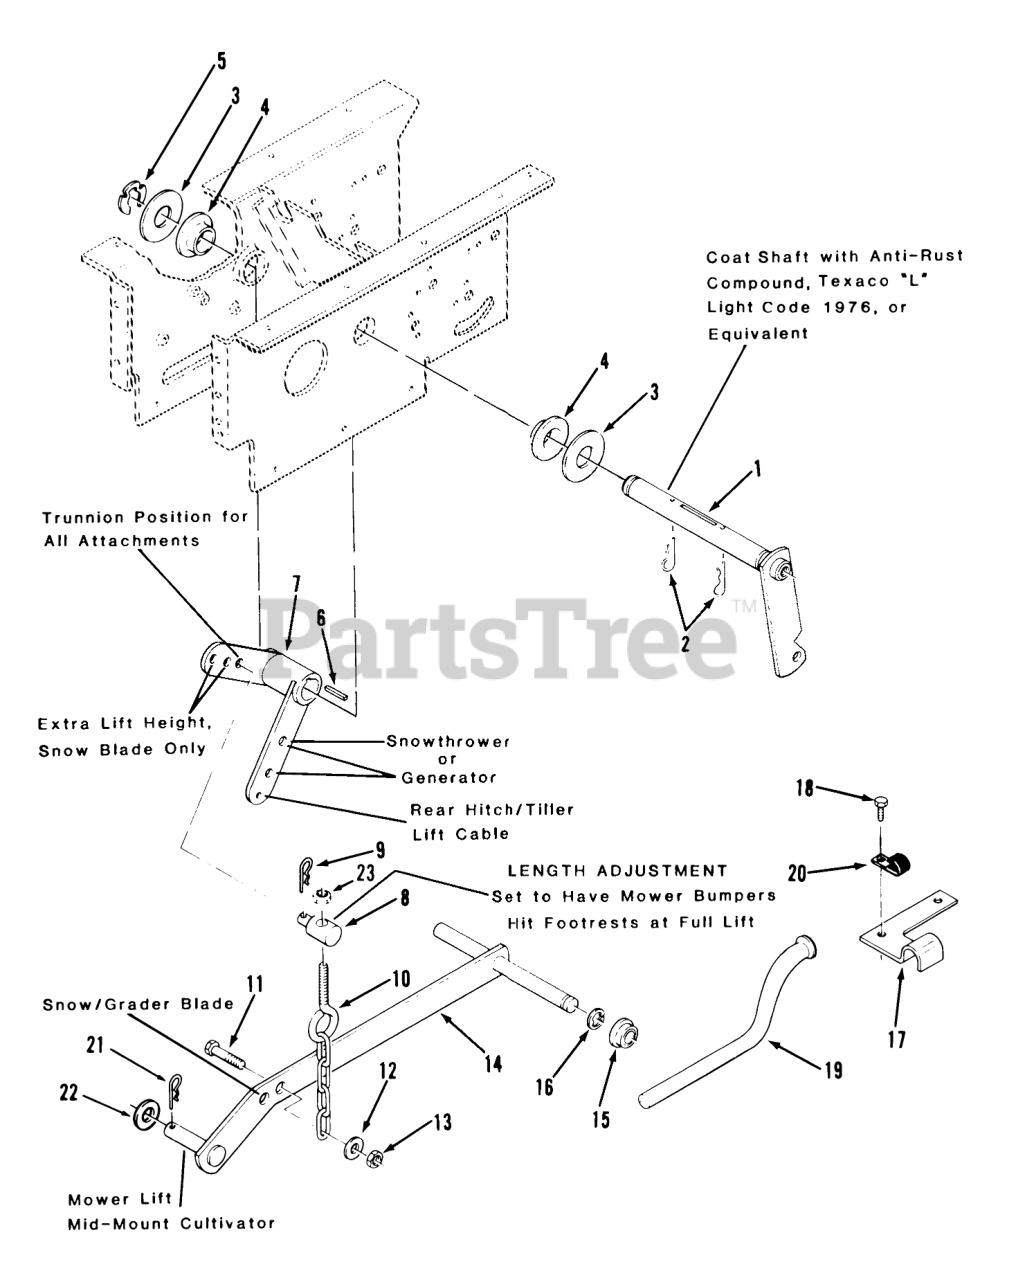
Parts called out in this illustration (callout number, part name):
1	Lift lever
1	Lift Lever
2	Pin-Cotter
3	WASHER
4	BEARING-FLANGE
5	Retainer
6	KEY-SQUARE
7	Bellcrank
8	TRUNNION-LIFT
9	Hairpin Cotter
10	CHAIN-LIFT
11	Bolt
12	WASHER 5/16 SAE
13	Nut
14	ASSY LIFT BAR R
15	BUSHING
16	E Ring
17	CLAMP-CONDUIT R
18	BOLT
19	TUBE-CONDUIT R
20	CLIP
21	Hairpin Cotter
22	Washer
23	NUT
